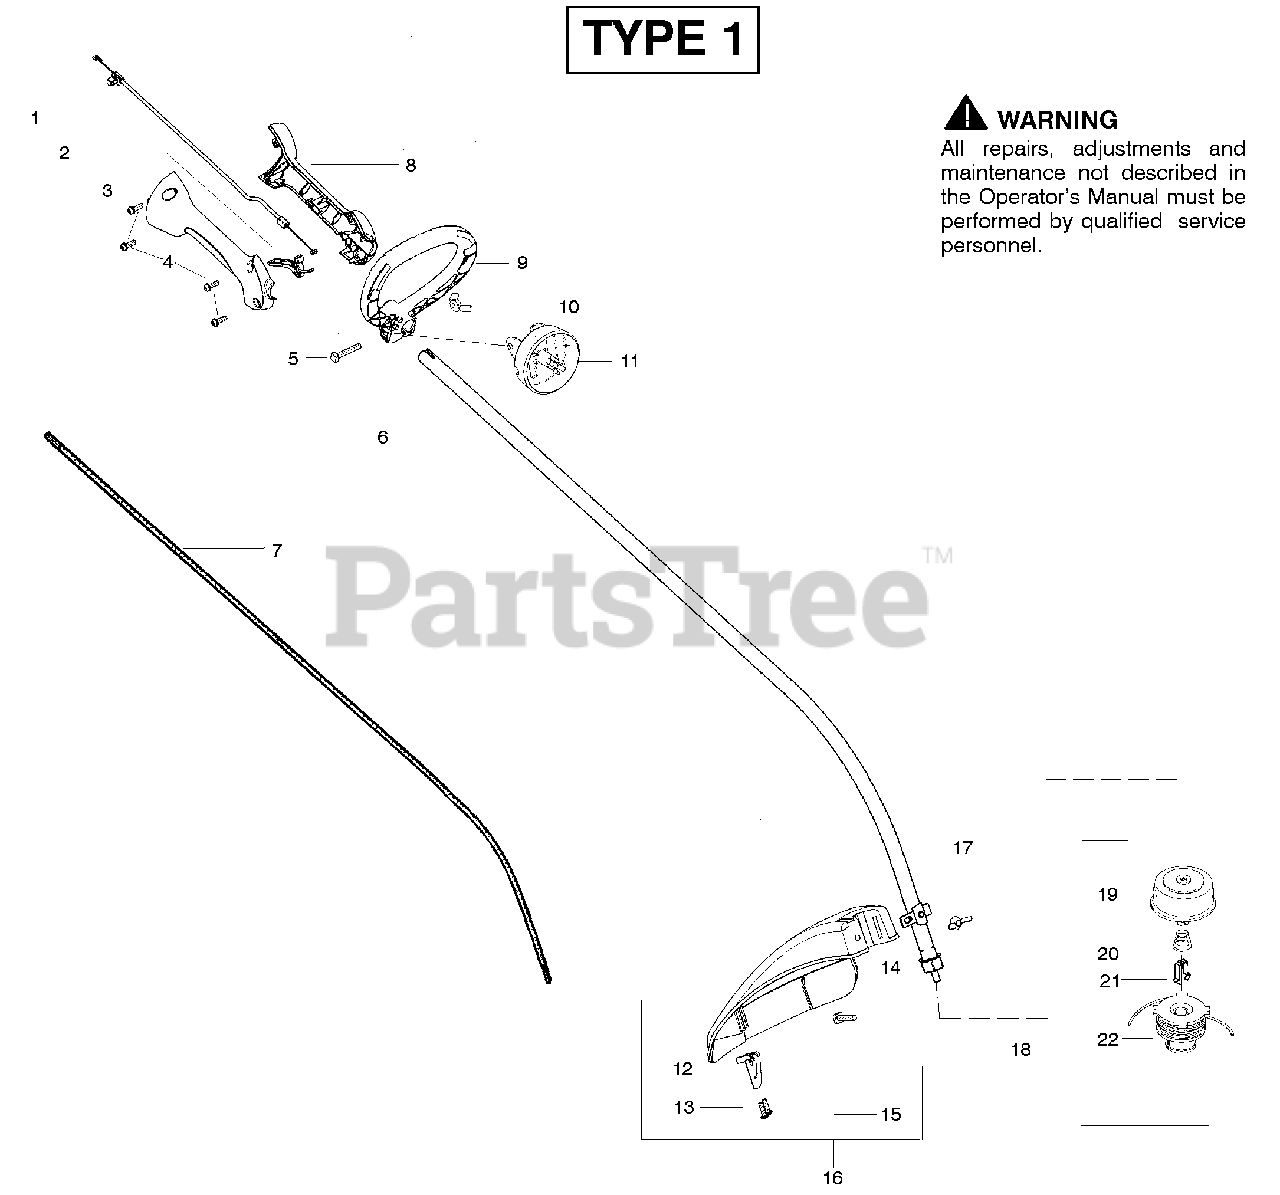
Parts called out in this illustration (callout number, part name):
1	Assy-Throttle Cable
3	Throttle Hsg. (Right)
4	Screw-Throttle Hsg.
5	Bolt-Handle
6	Kit-Drive Shaft Assy.
7	Shaft- Flex
8	Throttle Hsg. (Left)
9	Assy-Handle
10	Wingnut
11	Spool Buddy
12	Line Limiter
13	Screw-Line Limiter
14	Dust Cup
16	Kit-Shield Assy
17	Wingnut
18	Accy-TNG VI Cutting Head
19	Assy-Hub
20	Spring-Compression
21	Clip-Retainer-Head
22	Accy- Spool w/Line
